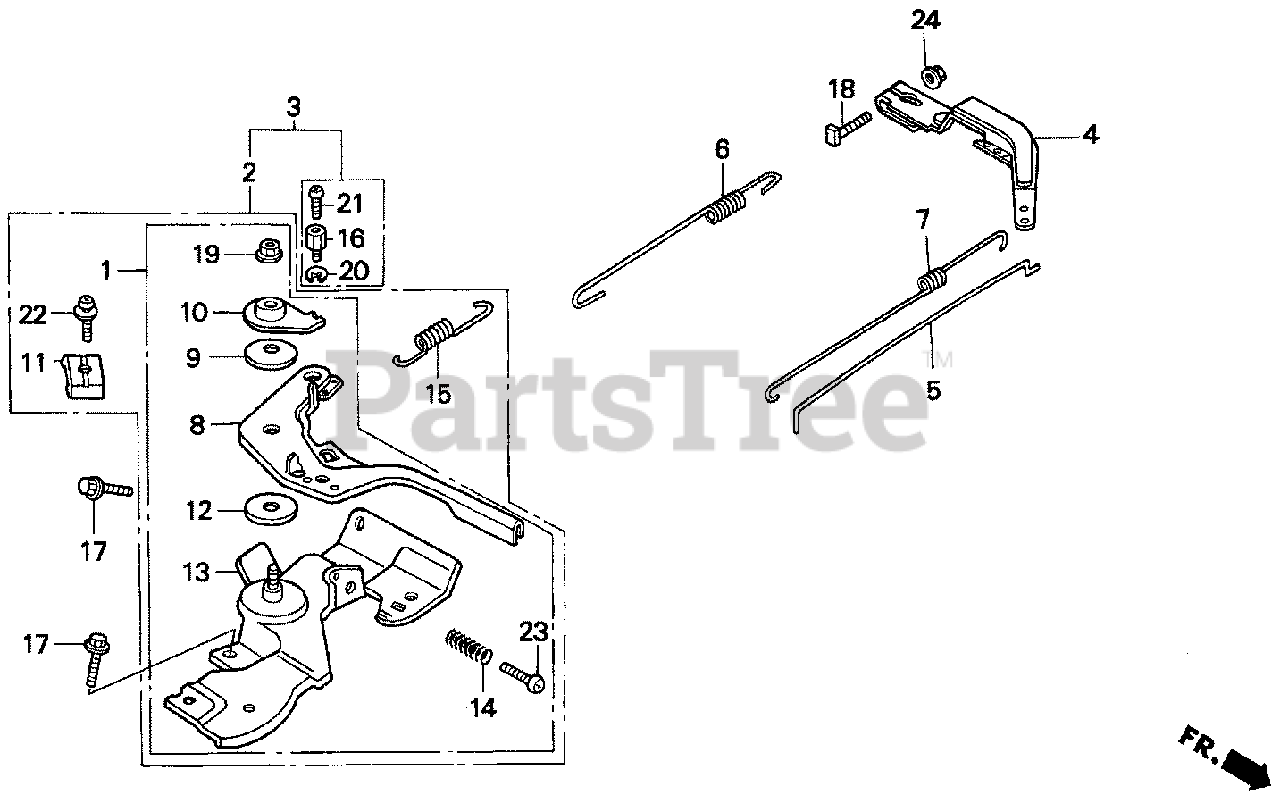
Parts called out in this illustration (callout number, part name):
2	CONTROL ASSY. (REMOTE)
4	ARM, GOVERNOR
5	ROD, GOVERNOR
6	SPRING, GOVERNOR
7	SPRING, THROTTLE RETURN
8	LEVER, CONTROL
9	SPRING, LEVER
10	WASHER, CONTROL LEVER
11	HOLDER, CABLE
12	SPACER, CONTROL LEVER
13	BASE, CONTROL
13	BASE, CONTROL (REMOTE)
14	SPRING, CONTROL ADJUSTING
15	SPRING, CABLE RETURN
17	BOLT, FLANGE (6X12) (CT200)
18	BOLT, GOVERNOR ARM
19	NUT, SELF-LOCK (6MM)
22	SCREW, PAN (5X16)
23	SCREW, PAN (5X25)
24	NUT, FLANGE (6MM)
